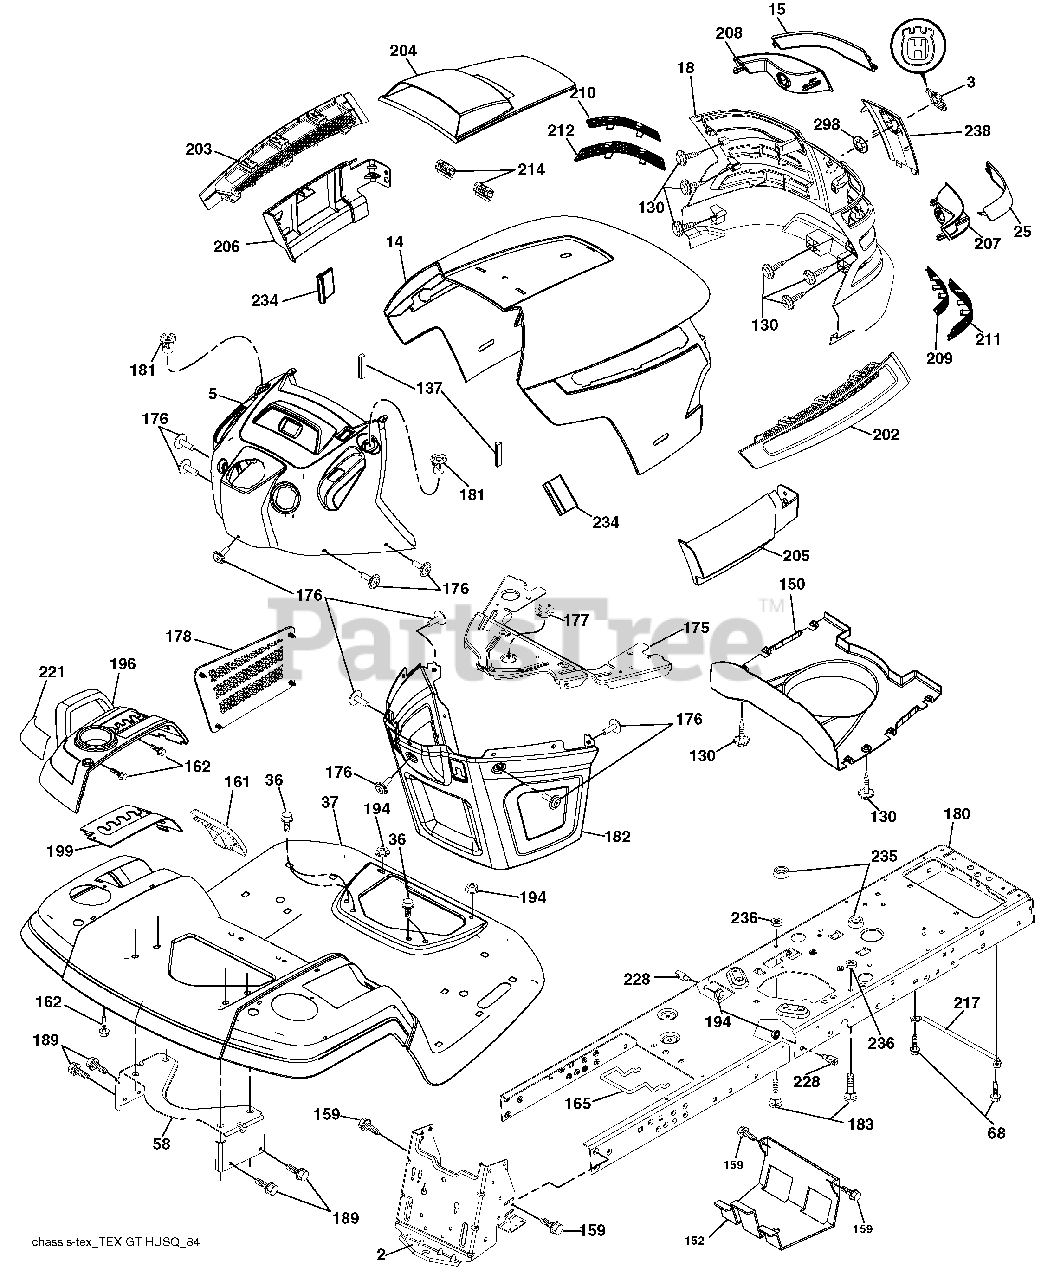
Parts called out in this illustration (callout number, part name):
2	Drawbar
3	Logo Husq.
14	Hood
18	Grille Asm
36	Screw 5/16-18 x 3/4
37	Fender
58	Bracket Fender
68	Screw 5/16-18 x 1/2
130	Screw #10 x 0.750 BOS Thread
137	Bumper Dash
150	Duct Heat Hood
152	Shield Browning/Debris
159	Screw 3/8-16 x 3/4
161	Console Fuel Window
162	Screw Hex Wsh Hi-Lo 1/4 x 1/2
165	Bracket Support Tank
175	Crossmember
176	Screw 10-24 x 5/8 Wshd Qdrx
177	Bushing Steering
178	Cargo Asm. Net
180	Chassis
181	Bushing Mtg. Fender Crgo.
182	Dash Lower
183	Bolt 5/16-18 x 1-1/4
189	Screw 5/16-18 x 3/4
194	Nut Lock Hex Flange 5/16-18
196	Console Asm. Deck Lift
199	Plate Deck Lift
202	Vent Side Hood RH
203	Vent Side Hood LH
204	Vent Asm Hood Top
205	Skirt Hood Side RH
206	Skirt Hood Side LH
209	Insert Hex Top RH
210	Insert Hex Top LH
211	Insert Hex Bottom RH
212	Insert Hex Bottom LH
214	Clip Retainer
221	Reflector LH
228	Stud Fastener
234	Bumper Hood
235	Spacer Fender
236	Nut Center Lock 5/16-18 unc
238	Trim Husq.
